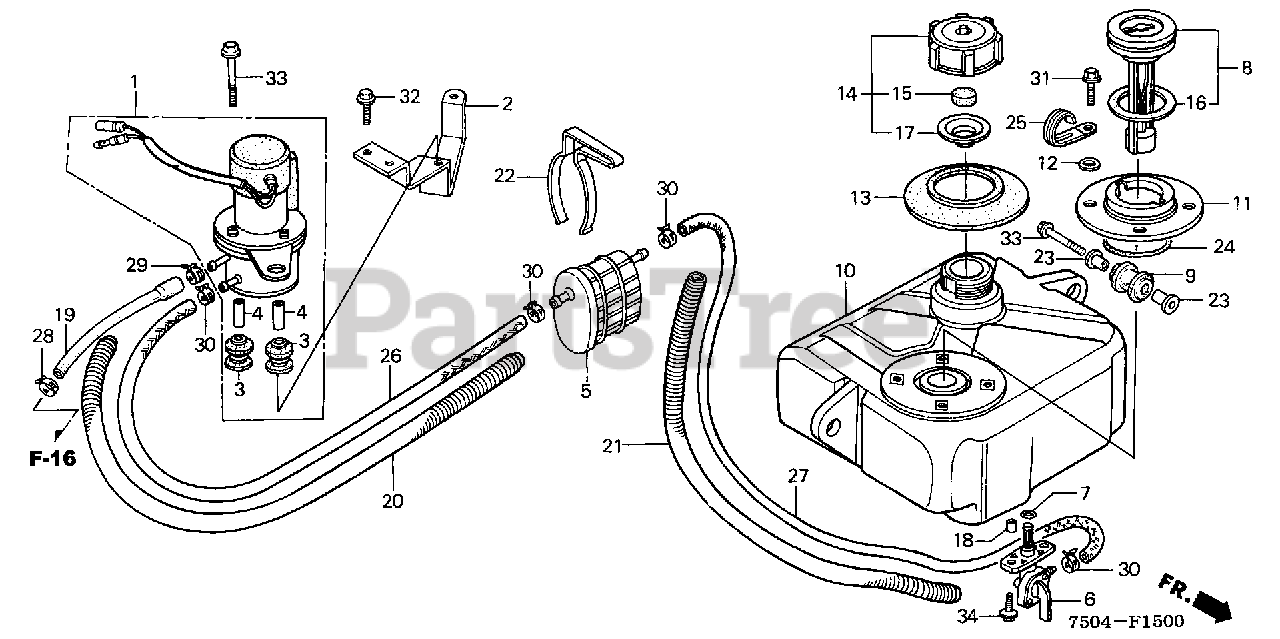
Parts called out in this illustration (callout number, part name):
1	PUMP ASSY., FUEL
2	STAY, FUEL PUMP
3	RUBBER, FUEL PUMP SETTING
4	COLLAR, FUEL PUMP DISTANCE
5	FILTER, FUEL
8	METER, FUEL
9	RUBBER, TANK SETTING
10	TANK, FUEL
11	FLANGE, FUEL METER UNIT
12	COLLAR, METER UNIT
13	SEAL, FUEL FILLER NECK
14	CAP, FUEL TANK
14	CAP ASSY., FUEL TANK
15	SPONGE, FUEL CAP BREATHER
16	GASKET C, FUEL METER
17	GASKET, FUEL CAP
19	TUBE, FUEL SPECIAL
20	TUBE A, CORRUGATED
21	TUBE B, CORRUGATED
22	CLAMP, FUEL STRAINER
23	COLLAR, FUEL TANK
24	O-RING (39.5X5)
25	CLIP, WIRE HARNESS
26	BULK HOSE, FUEL (5.5X8000) (5.5X250)
27	BULK HOSE, FUEL (5.5X8000) (5.5X300)
27	BULK HOSE, FUEL (5.5X8000) (5.5X230)
28	CLIP, TUBE (D8)
29	CLIP, TUBE (D8.5)
30	CLIP, TUBE (D10.5)
31	BOLT, FLANGE (6X10)
32	BOLT, FLANGE (6X12)
33	BOLT, FLANGE (6X32)
